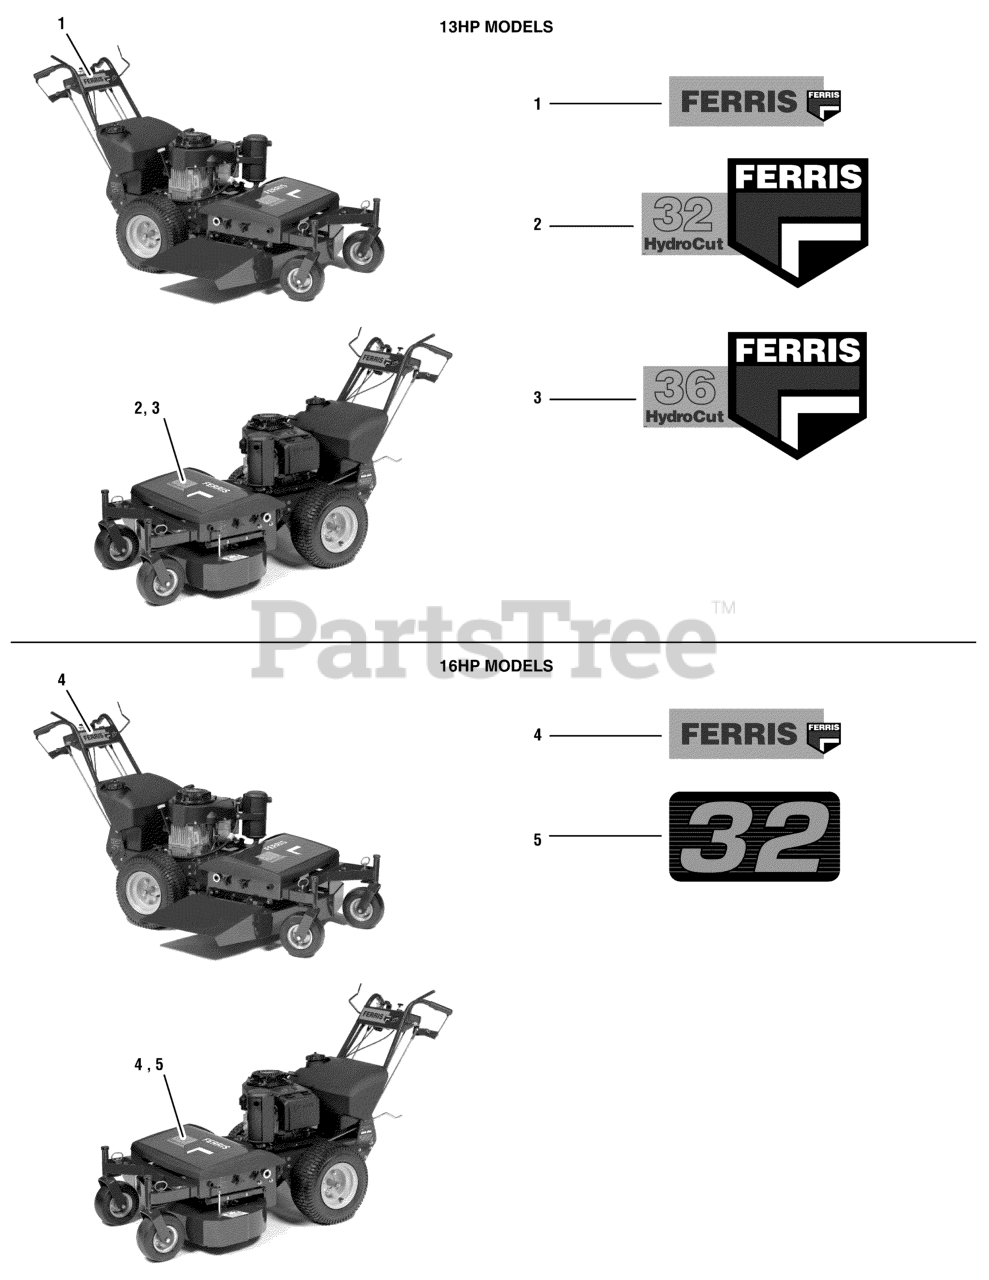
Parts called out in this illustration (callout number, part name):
1	DECAL, FERRIS TEXT & LOGO
2	DECAL, HydroCut 32
3	DECAL, HYDROCUT 36
4	DECAL, FERRIS TEXT & LOGO
5	DECAL, 32" DECK, SILVER
